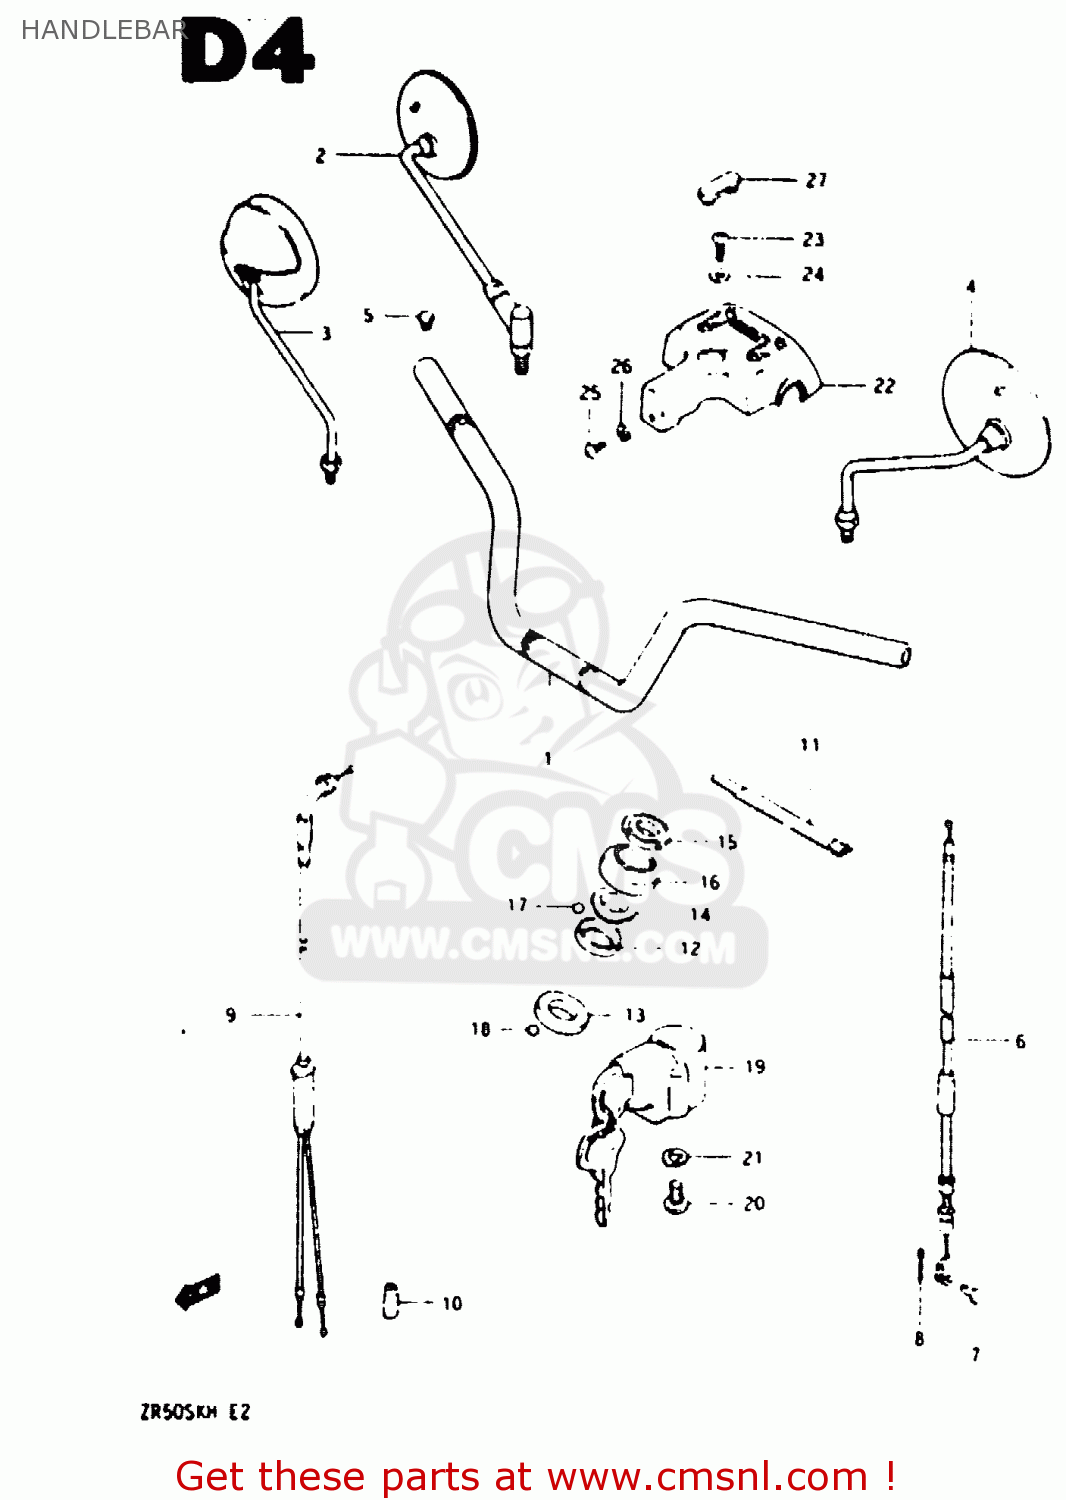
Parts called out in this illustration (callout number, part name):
1	HANDLEBAR
2	MIRROR ASSY, REAR VIEW
3	MIRROR ASSY, REAR VIEW
4	MIRROR, REAR VIEW LH
5	CAP
6	CABLE ASSY,CLUTCH
7	PIN(L:13)
8	PIN
9	CABLE ASSY,THROTTLE
10	SEAL,DUST(7X18X30)
11	CLAMP
12	RACE,STEERING INNER UPR
13	LACE,STEERING INNER LWR
14	RACE,STEERING OUTER UPR
15	NUT,STEERING STEM(25X44X10)
16	DUST SEAL,STEERING UPR
17	BALL
18	BALL
19	LOCK ASSY,STEERING
20	SCREW
21	LOCK WASHER
22	COVER, STEERING HEAD
23	SCREW 6X12
24	WASHER
25	SCREW
26	WASHER,5MM
27	CAP,PILOT LAMP BOLT
